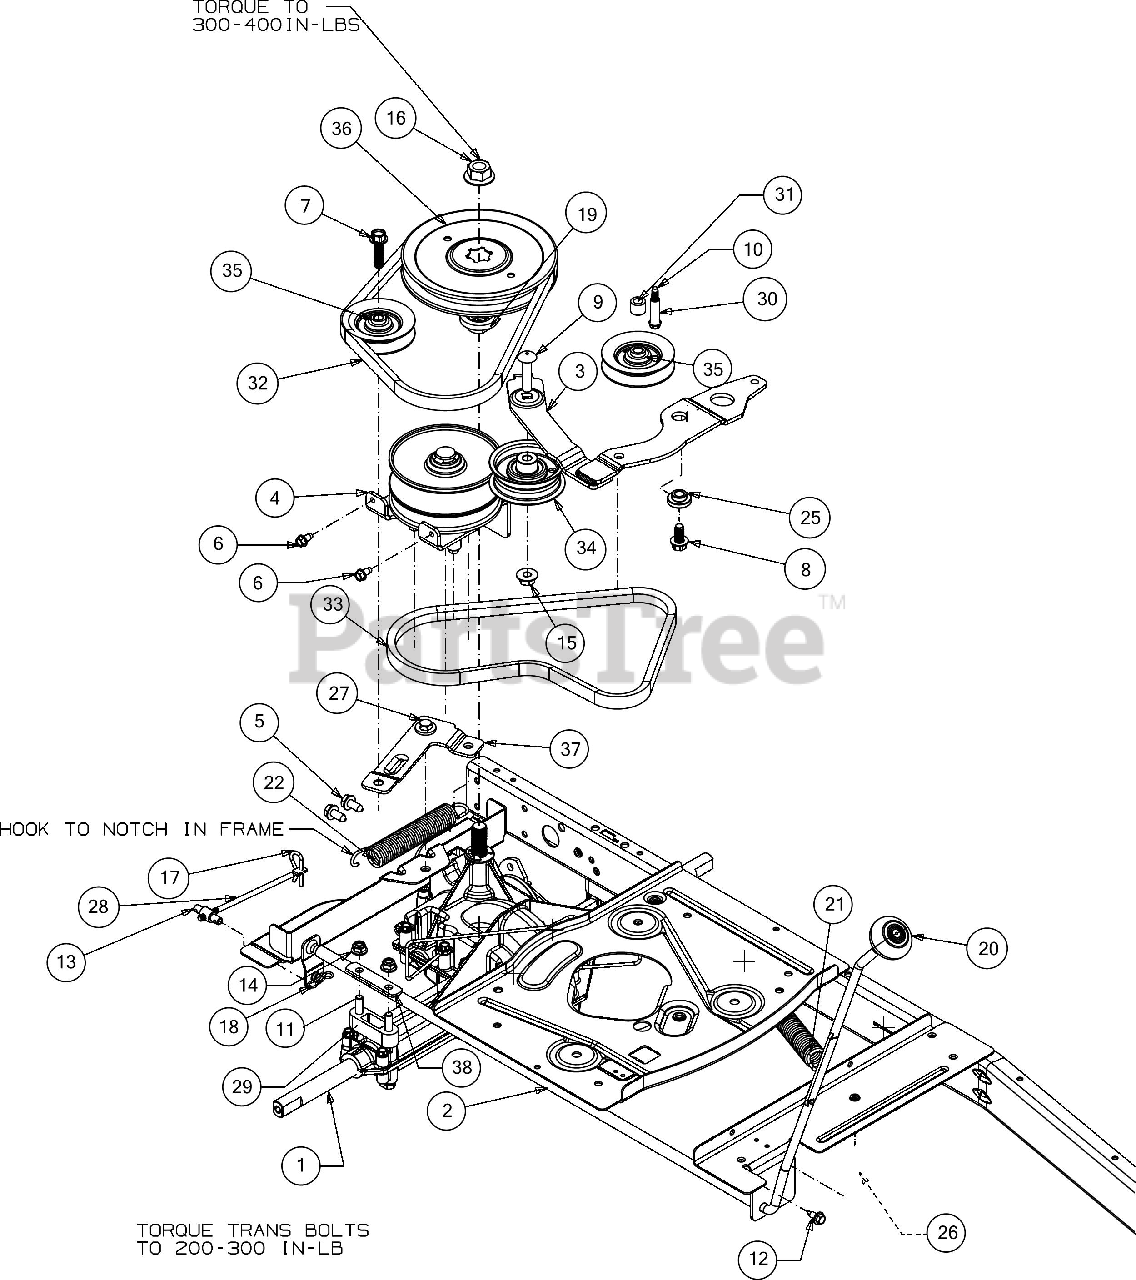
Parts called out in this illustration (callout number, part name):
1	TRANSMISSION ASSEMBLY
2	SHIFT HANDLE ASSEMBLY
3	DRIVE IDLER ASSEMBLY
4	BRACKET ASSEMBLY
5	SCREW 5/16-18 x .750
6	SCREW 1/4-20 X.500
7	SCREW 3/8-16 x 1.375
8	SCREW 3/8-16 x 3/4
9	BOLT 3/8-16 x 1.69 GR5
10	SCREW 1/4-20 x 1.750
11	SCREW 5/16-18X3.5 GR5
12	SCREW 1/4-20X.625
13	ADJUSTUSTMENT FERRULE 1/4-20 x 1.00
14	FLANGE LOCK NUT 5/16-18
15	FLANGE LOCK NUT
16	FLANGE NUT W/HUB
17	COTTER PIN
18	BOW TIE COTTER PIN 1/4-5/16
19	PULLEY HUB
20	SHIFT KNOB
21	EXTENSION SPRING .94 x 6.74
22	EXTENSION SPRING
25	SHOULDER SPACER 1.00 x .38 x .38
26	SCREW-SHOULDER SCREW .368 X .75 X 1/4-20
27	SHOULDER SCREW .560X.165
29	TRANSAXLE SPACER
30	SPACER:.260 x .372 x 1.420
32	V-BELT 5L x 35.25
33	V-BELT 5L x 35.25
34	FLAT IDLER PULLEY 2.75 OD
35	V-IDLER PULLEY A x 3.06 OD
36	V-TYPE PULLEY 6.56 DIA"
37	IDLER BRACKET REAR
38	TRANSAXLE BRACKET
